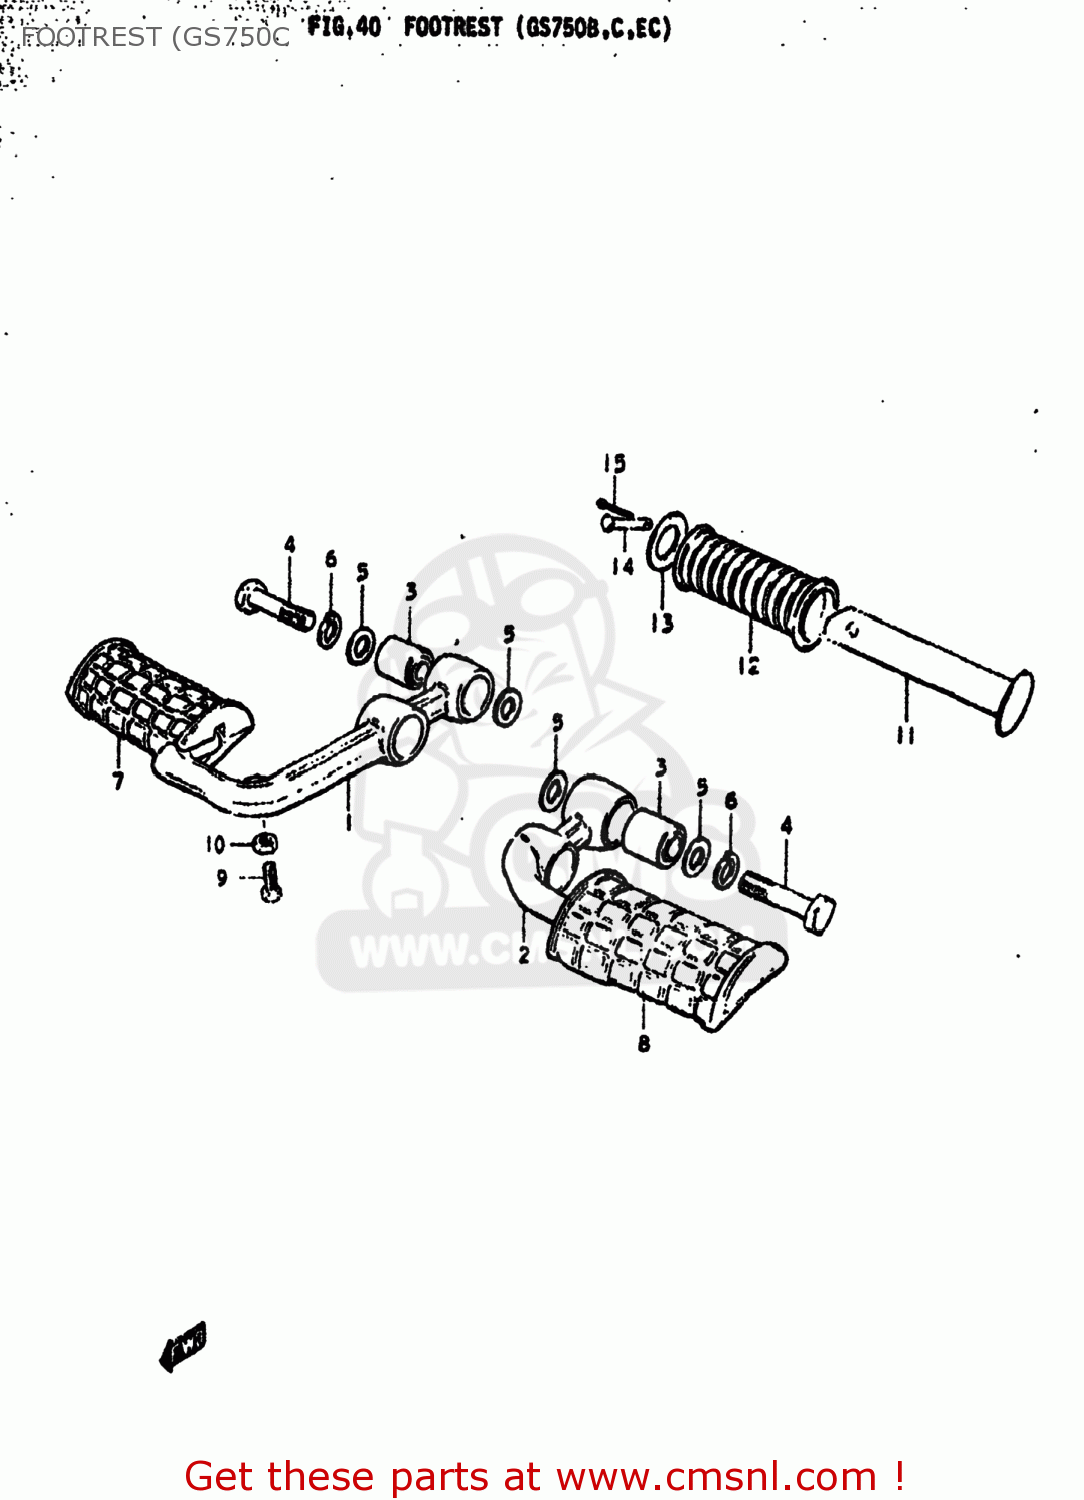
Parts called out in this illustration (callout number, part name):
1	BAR,FRONT FOOTREST,RIGHT
2	BAR,FRONT FOOTREST,LEFT
3	BUSH
4	BOLT
5	WASHER (10.1X21X2.3)
6	LOCK WASHER
7	RUBBER,FR FOOTREST,R
8	RUBBER,FOOTREST
9	BOLT
10	NUT 6MM
11	BAR,FOOTREST RUBBER
12	RUBBER,PILLION FOOTREST
13	WASHER (19.5X32X2)
14	PIN
15	PIN 20X20
